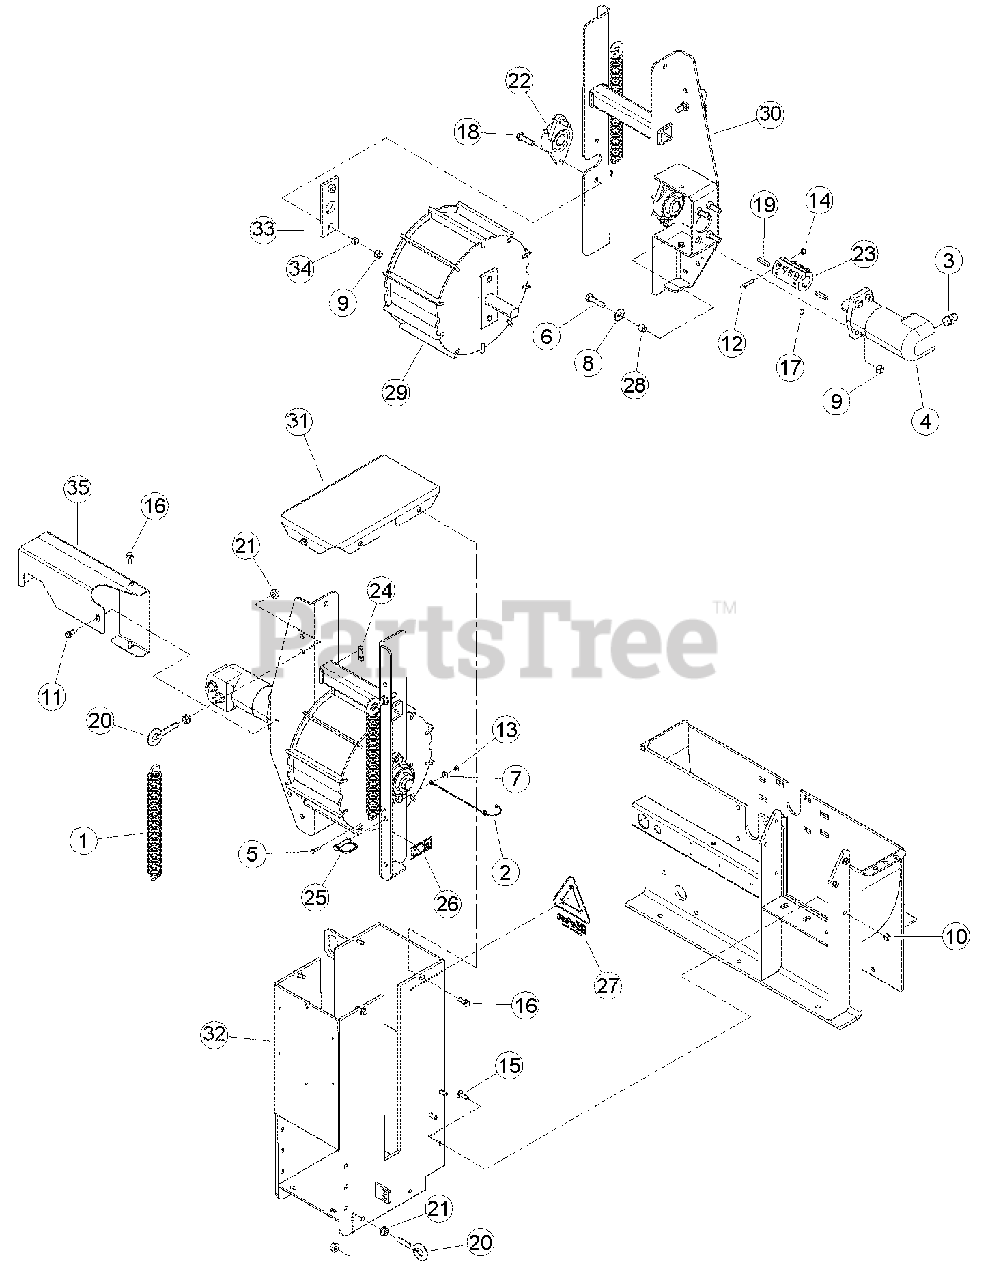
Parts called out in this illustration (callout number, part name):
1	SPRING, EXTENSION
2	LANYARD, NYLON
3	ADAPTER, -10 MORING / -8 MJIC
4	MOTOR, 24 CU IN HYDRAULIC
5	BOLT, 1/4 X 1 HEX HD GR5 ZP
6	BOLT, 1/2 X 2 HEX HD GR5 ZP
7	WASHER, 1/4 FLAT ZP
8	WASHER, 1/2 FLAT ZP
9	NUT, 1/2 CENTERLOCK GRB ZP
10	NUT, 3/8 SERR FLANGE NC ZP
11	SCREW, 3/8-16 X 1 LG THD CUTT ZP
12	BOLT, 5/16 X 1-1/2 HEX HD GR5 ZP
13	NUT, 1/4 NE NYLOCK ZP
14	NUT, 5/16 NE NYLOCK ZP
15	BOLT, 3/8 X 1-1/4 CRG GR5 NC ZP
16	BOLT, 3/8 X 1 SERR FLANGE GR5 NC ZP
17	SET SCREW, 3/8 X 1/2 CUP PT SKT
18	BOLT, 1/2 X 1-3/4 HEX HD GR5 NC ZP
19	KEY, 5/16 SQUARE X 1-1/2 LONG
20	EYEBOLT, 1/2 X 2" ZP
21	NUT, 1/2 SERR FLANGE NC ZP
22	BEARING, 1-1/4" DIA 2 BOLT FLANGE
23	COUPLER, 1-1/4" SHAFT
24	WEAR PAD, STD.SPRING HD FRONT
25	PIN, 3/8 X 1-1/2 SNAP USABLE LGH
26	DECAL, CRUSHING ISO
27	DECAL, CHIP IT
28	SPACER, 0.75 X 0.620
30	WELDMENT, ROLLER SLIDE
31	WELDMENT, TOP ROLLER COVER
32	WELDMENT, ROLLER SUPPORT
33	BEARING, SLIDE
34	SPACER, .75 OD X .5 ID X .37
35	WELDMENT, HYD MOTOR COVER
